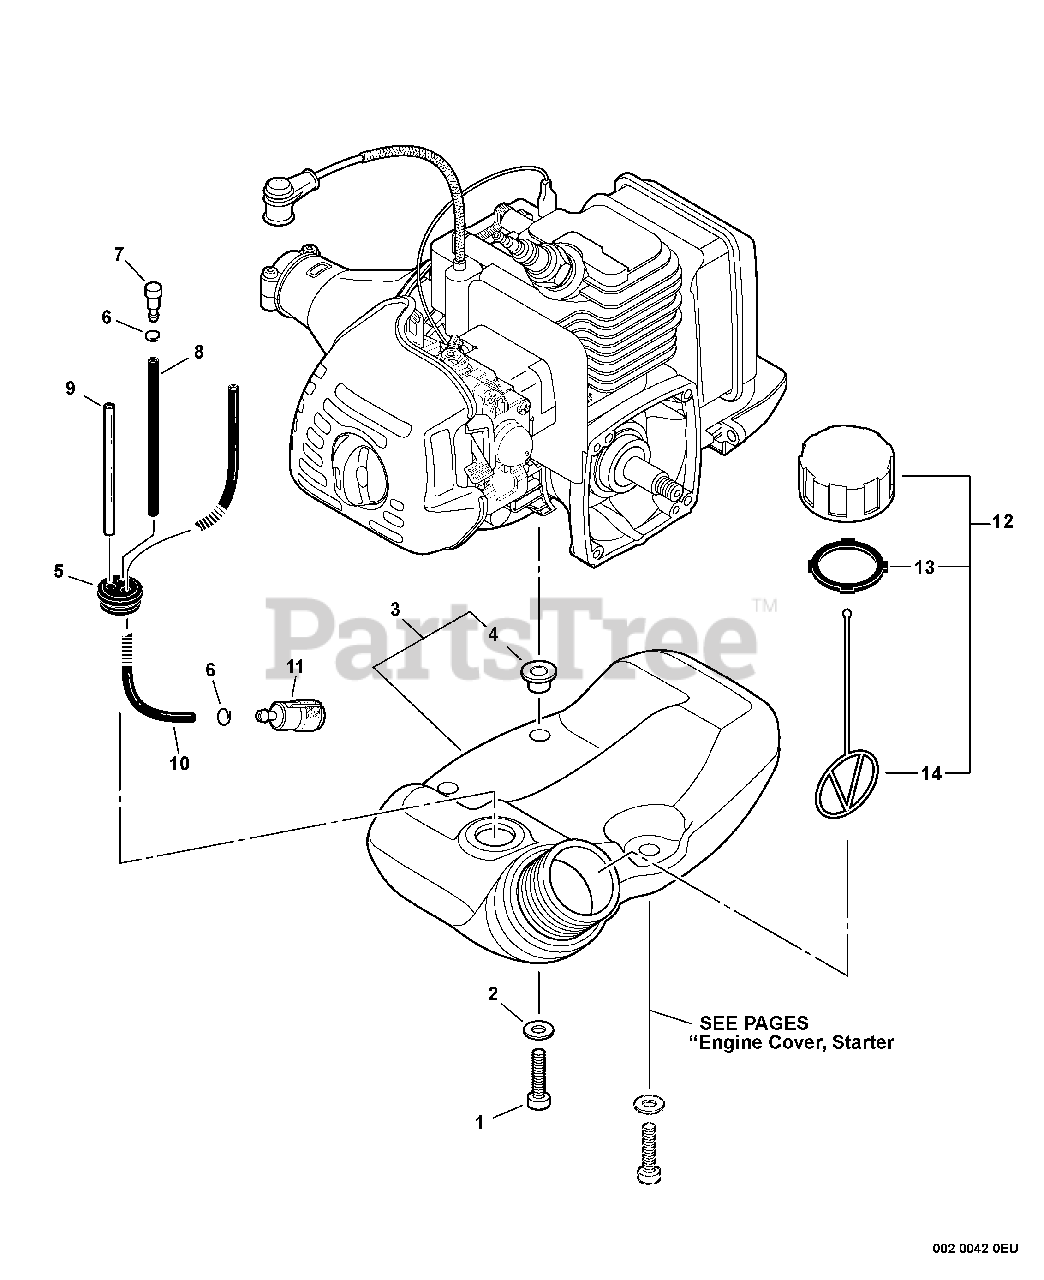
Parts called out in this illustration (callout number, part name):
1	SCREW - 5X20
2	WASHER - 5
3	TANK, FUEL
4	COLLAR - 5
5	GROMMET
6	CLIP - 6
7	VENT, FUEL TANK
8	PIPE - 3X5X90 -- BLACK
9	PIPE - 3X6X80 -- CLEAR
10	PIPE - 3X5X180 -- BLACK
11	FILTER, FUEL
12	CAP ASSY
13	GASKET, CAP
14	CONNECTOR, CAP
